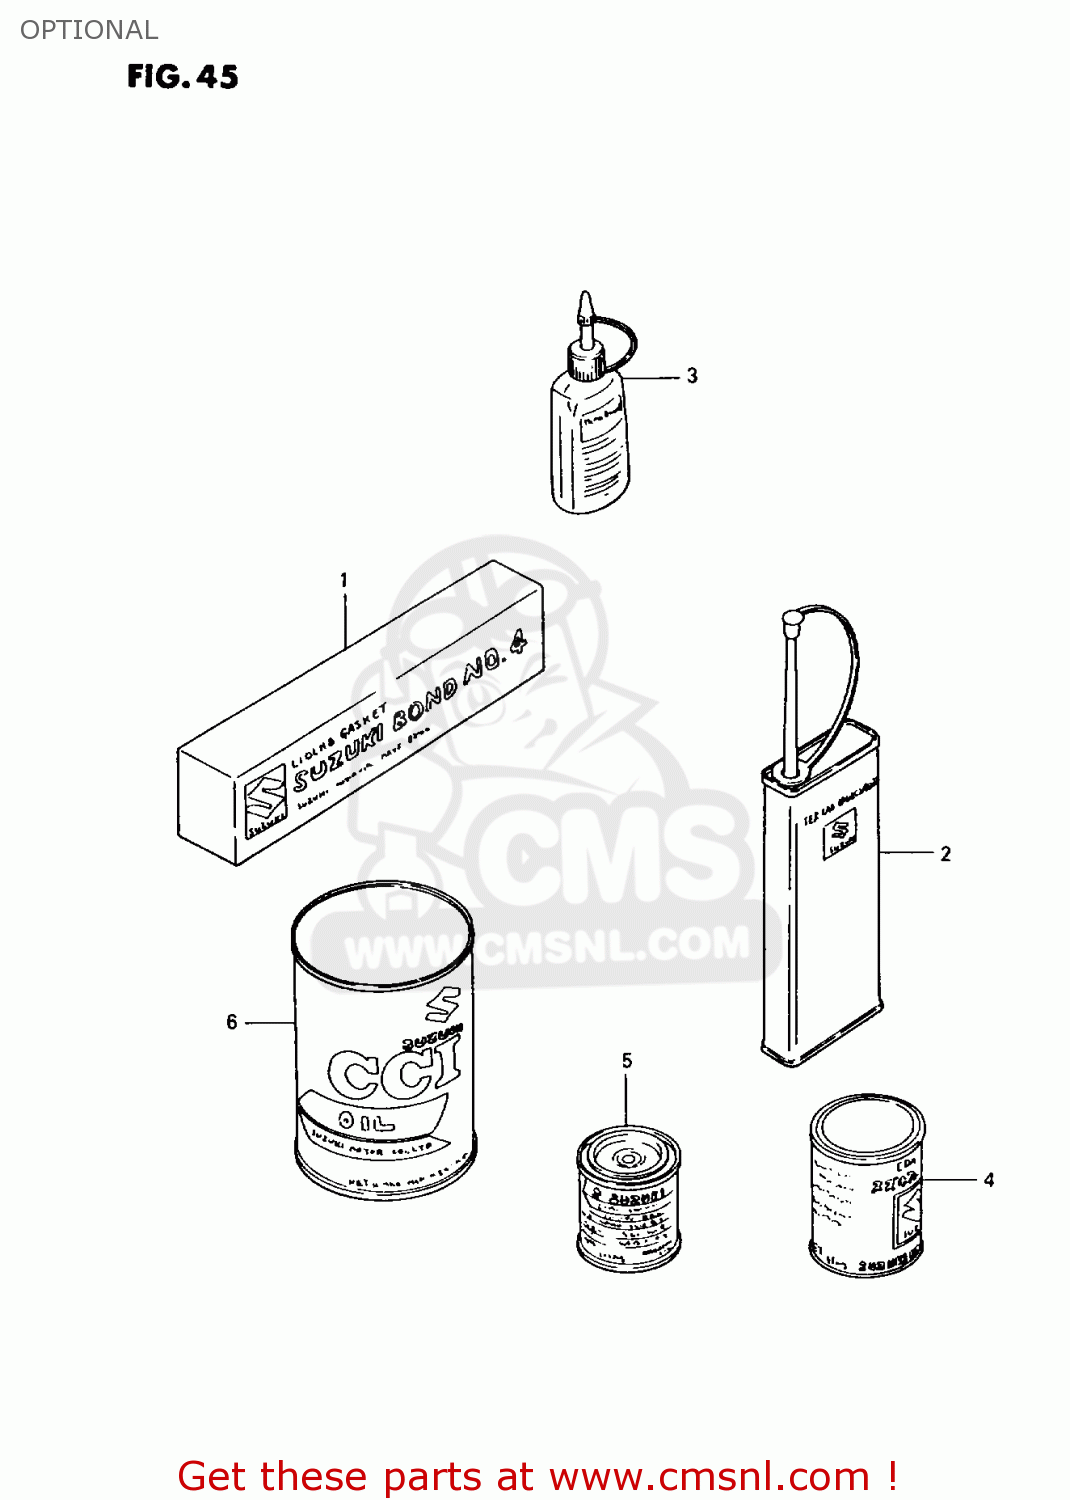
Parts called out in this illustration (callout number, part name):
1	BOND 1104
2	THREAD LOCK NO.1401 CLEAR 200G
3	THREAD LOCK NO
4	GREASE(C)EP2 LITHIUM 150G
5	PAINT,BLACK
6	CCI OIL
